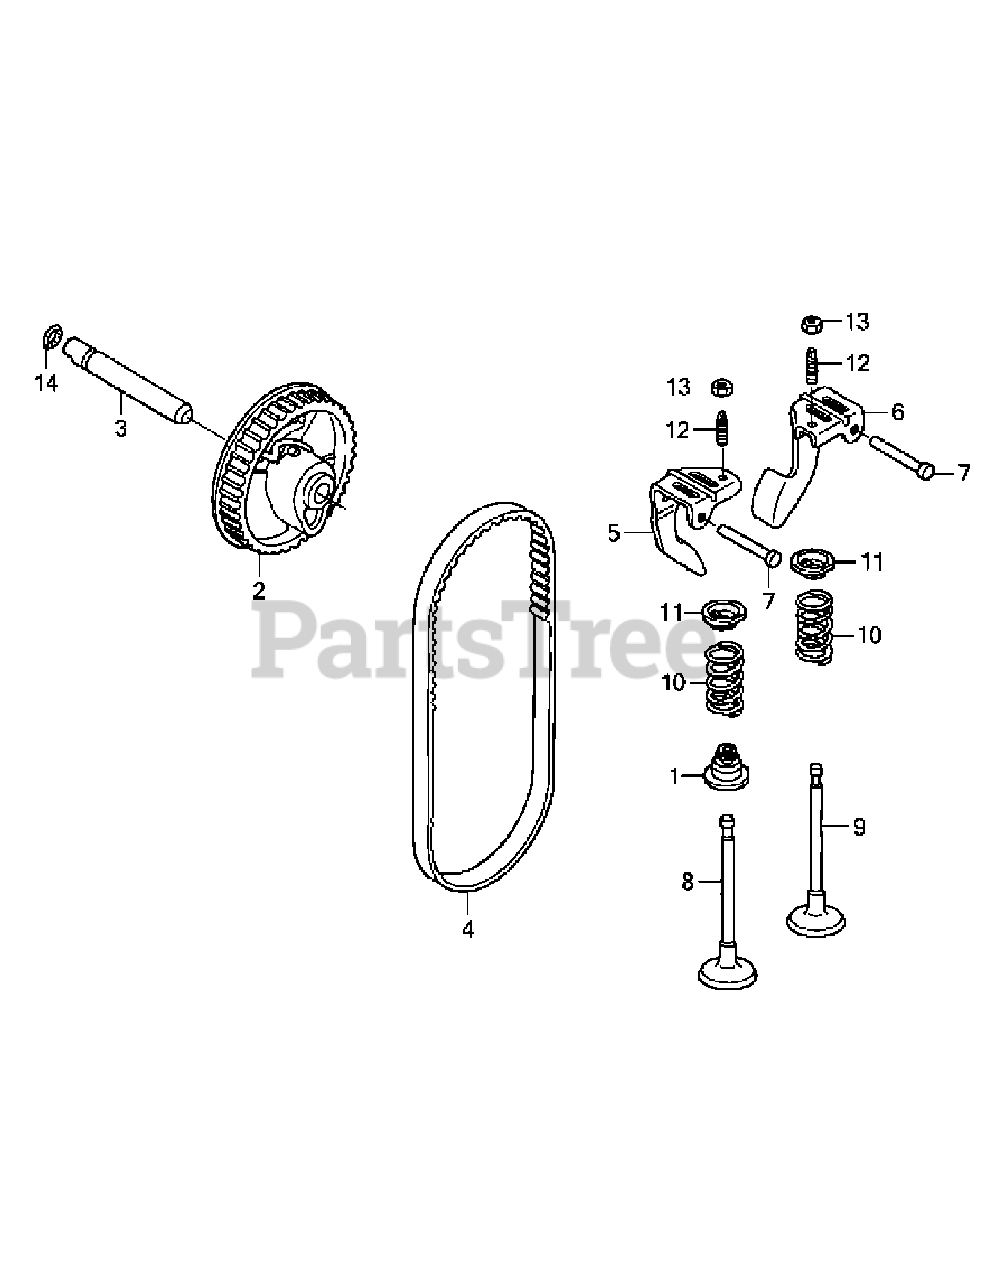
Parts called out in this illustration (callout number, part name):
1	Seal, Valve Stem
2	Pulley Comp., Camshaft
3	Shaft, Cam Pulley
4	Belt, Timing (84Hu7 G-200)
5	Arm, In. Valve Rocker
6	Arm, Ex. Valve Rocker
7	Shaft, Rocker Arm
8	Valve, In. (Technostar)
9	Valve, Ex. (L8E)
10	Spring, Valve
11	Retainer, Valve Spring
12	Screw, Tappet Adjusting
13	Nut, Tappet Adjusting
14	O-Ring, 6.8X1.9 (Arai)
